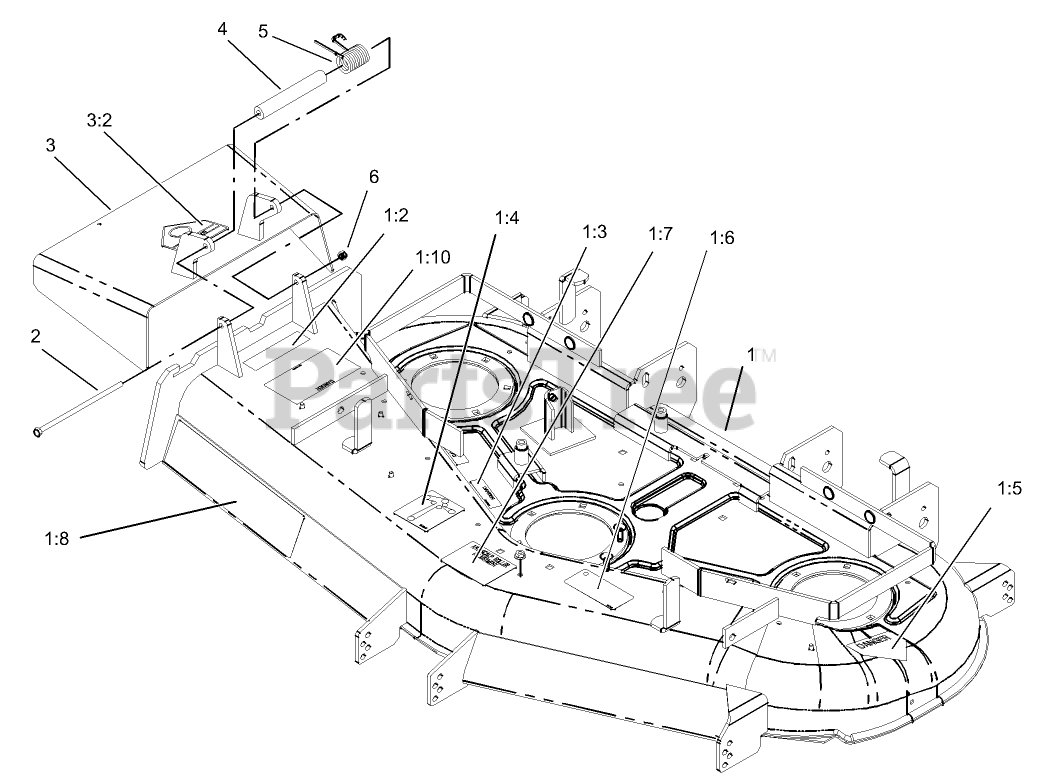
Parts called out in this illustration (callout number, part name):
1	Deck ASM
1:2	DECAL-WARNING
1:3	DECAL-COVER, MISSING
1:4	DECAL-ROUTING, BELT
1:5	DECAL-DANGER
1:6	DECAL-TORQUE, BLADE BOLT
1:7	DECAL-WHEEL, GAGE
1:8	DECAL
1:10	DECAL-DANGER, THROWN OBJECT
2	SCREW-HH
3	Deflector ASM
3:2	DECAL-DANGER
4	SPACER
5	SPRING-TORSION
6	NUT-LOCK, NI
